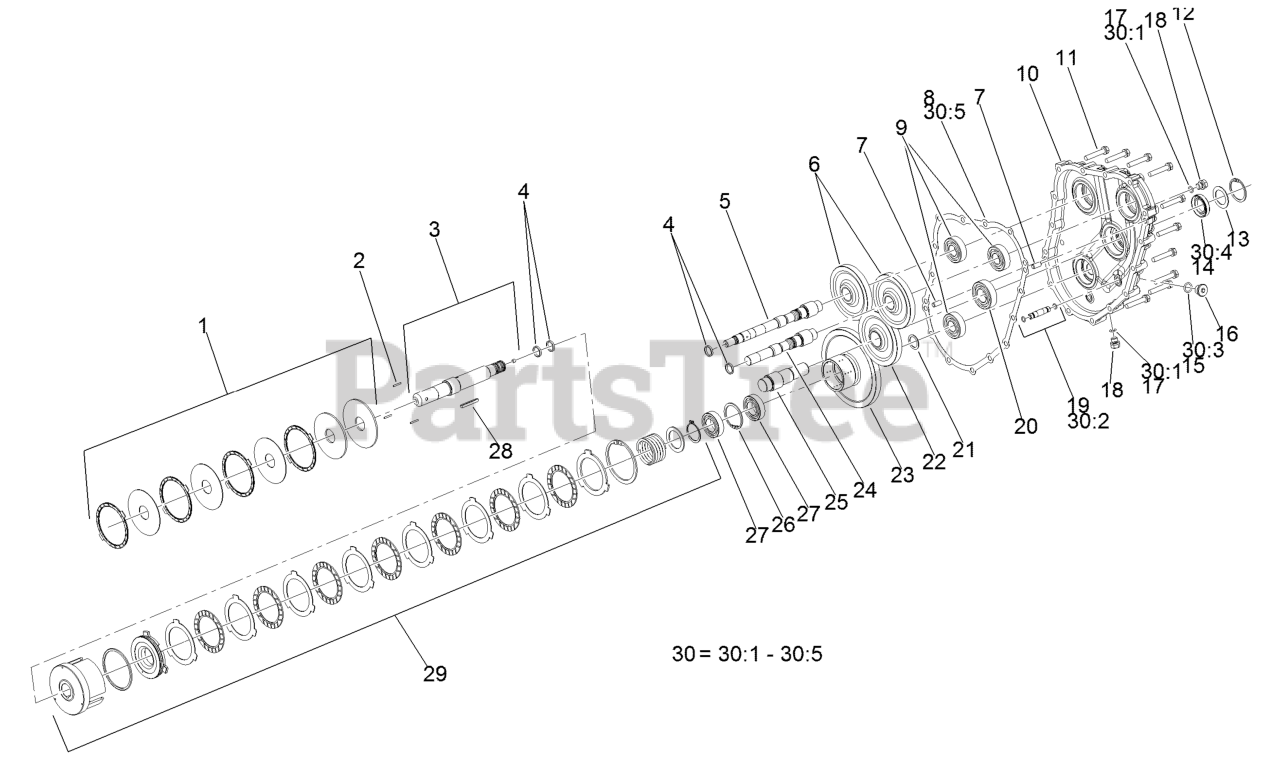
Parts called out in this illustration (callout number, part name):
1	PTO Brake ASM
2	Rod-Push
3	PTO Shaft ASM
4	Ring-Seal
5	Shaft-Pump
6	Gear-Pump
7	Pin-Parallel
8	Gasket-Housing, Gear
9	Bearing
10	Housing-Case, Gear
12	Ring-Snap
15	Packing
16	Plug-NPTF
17	O Ring-Plug
20	Bearing
22	Gear-Input
23	Gear-PTO
24	Shaft-Pump
25	Shaft-Input
26	Ring-Snap
27	Bearing
29	Clutch Cylinder ASM
30	Gear Housing Seal Kit
30:1	O Ring-Plug
30:2	O-Ring
30:3	Packing
30:5	Gasket-Housing, Gear
